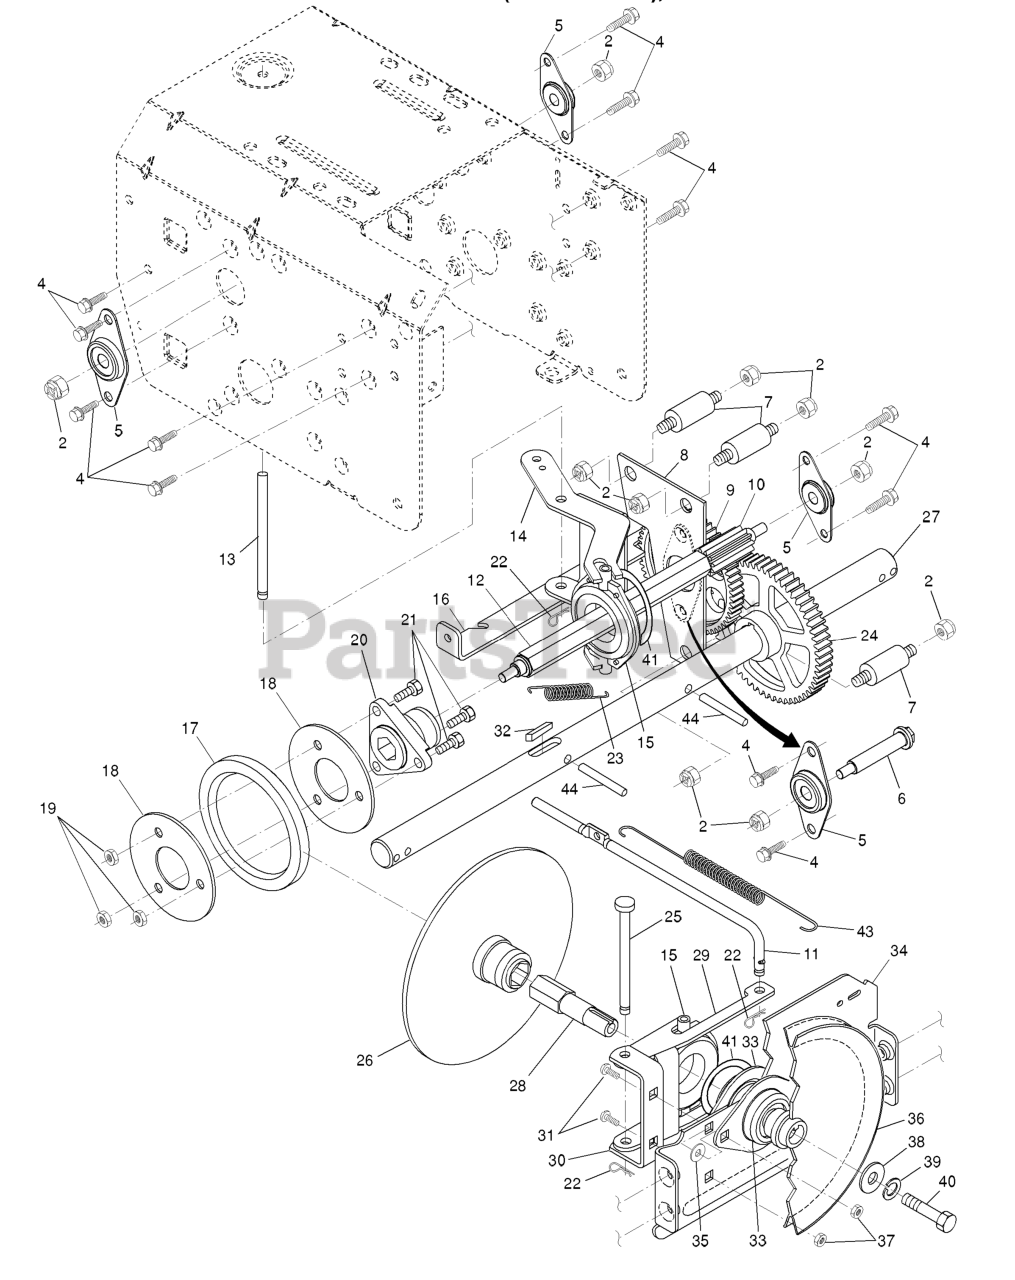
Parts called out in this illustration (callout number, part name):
2	NUT.LOCK.5/16-18
4	Screw, Hex Head 5/16-18 x 1/2
5	BEARING, FLANGE
6	SHAFT, AUXILIARY
7	SPACER, PLATE
8	AUXILLARY PLATE
9	GEAR, INTERMEDIATE
10	GEAR, PINION
11	ROD.CLUTCH.YELLOW.ZINC
12	SHAFT.HEX.LONG
13	PIN, PIVOT
14	LEVER, SPEED CONTROL
15	TRUNNION BEARING ASSY
16	BRACKET, PIVOT, SHIFT
17	RING, RUBBER WHEEL
18	PLATE.RUBBER.WHEEL
19	NUT.CENTERLOCK.5/16-
20	HUB, RUBBER WHEEL
21	BOLT
22	RETAINER CLIP PM
23	SPRING, BIAS
24	GEAR, AXLE (58T)
25	PIN, PIVOT LEVER
26	DRIVE PLATE WELDMENT
27	SHAFT.AXLE.POWER.STEERING
28	SHAFT.HEX.SHORT
29	LEVER.SHIFTER.PLATE.BLACK
30	BRACKET, SHIFTER SUPPORT
31	BOLT
32	KEY, SQUARE 1/4 X .875
33	BEARING FLANGE
34	PLATE.DRIVE.MOUNTING.BLACK
35	SPACER, BEARING
36	PULLEY.TRACTION.7.75
37	NUT.FLANGE.5/16
38	WASHER, FLAT
39	WASHER.LOCK.HVY.HLCL.SPR.5/16
40	Screw, Hex Head 5/16-18 x 3/4
41	RETAINING RING (2 2)(3 2)
43	SPRING.RETURN
44	PIN.ROLL.3/16
